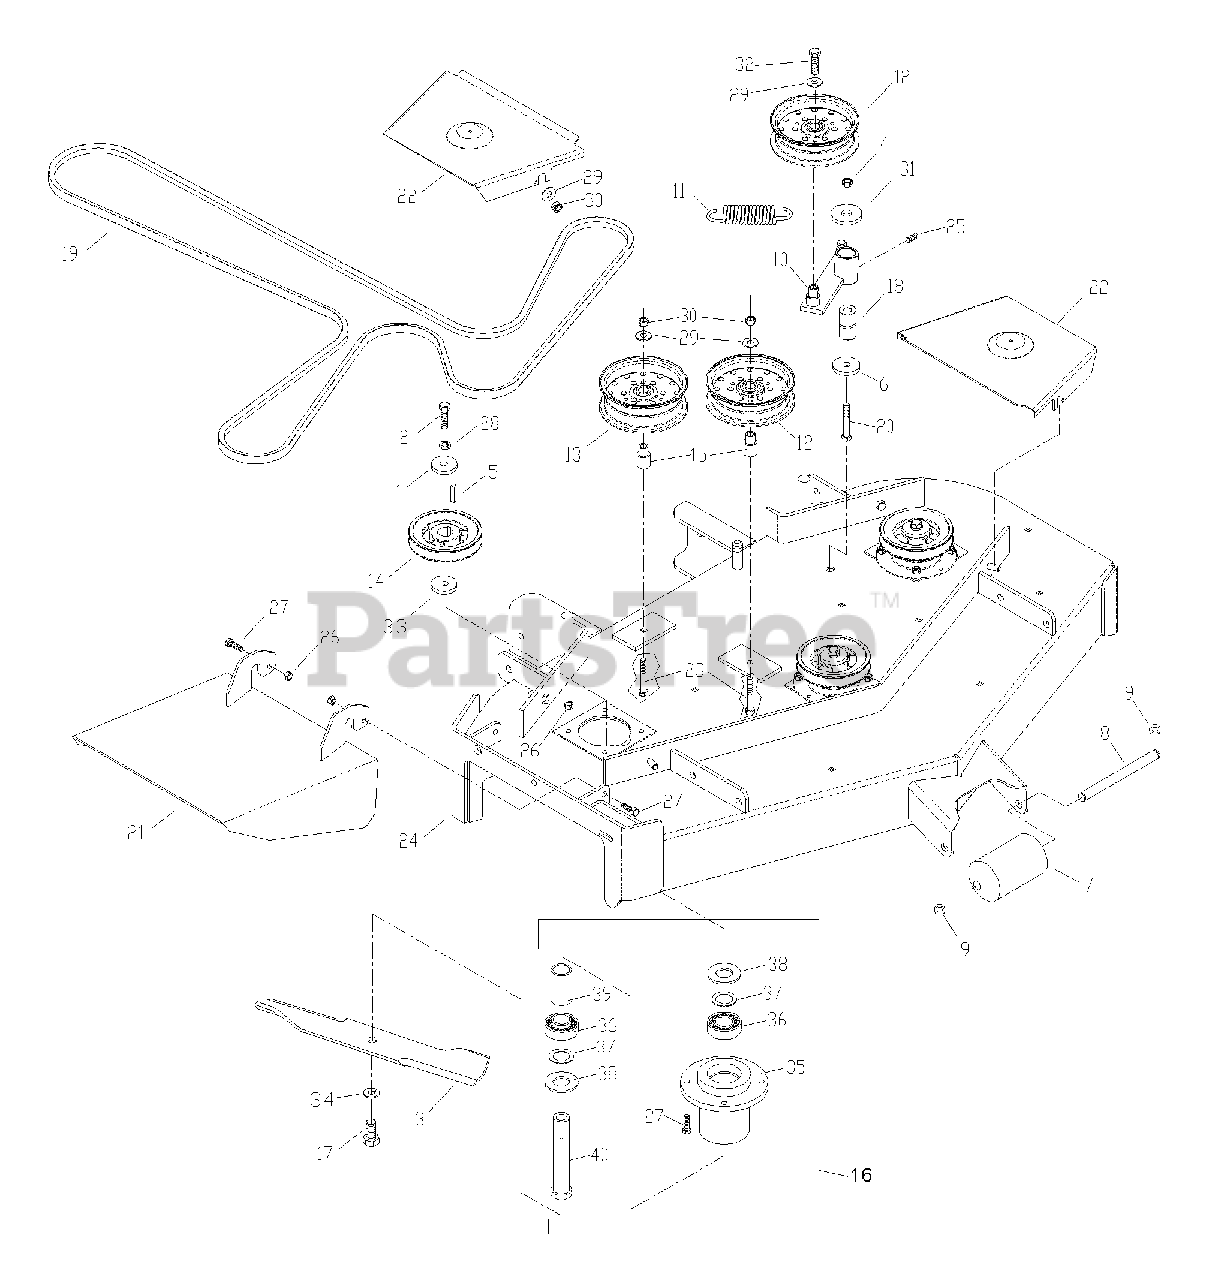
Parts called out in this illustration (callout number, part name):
1	HEAVY WASHER
2	HCS 7/16 X 1.500
3	BLADE 14.875
4	NUT 1/2 NYLOC
5	KEY 1/4 X 1.125
6	SUPPORT WASHER
7	ANTI-SCALP ROLLER
8	ROLLER AXLE
9	E-RING 1/2
12	IDLER PULLEY
13	IDLER PULLEY
15	IDLER BUSHING
16	COMPLETE HOUSING
17	HCS 5/16 X 1.250
18	PIVOT BUSHING
19	BELT
20	HCS 1/2 X 3.250
21	DEFLECTOR CHUTE
22	BELT SHIELD
23	HCS 3/8 X 2.500
24	DECK W/DECALS
25	ZERK
26	NUT 5/16 CTR. LOCK
27	HCS 5/16 X 1.000
28	WASHER 7/16 LOCK
29	WASHER 3/8 FLAT
30	NUT 3/8 CTR. LOCK
31	WASHER 1/2 FLAT
32	HCS 3/8 X 1.00 SERR. HD.
33	MACH. BUSHING
34	WASHER 5/8 LOCK
36	BEARING
37	MACH. BUSHING
38	MACH. BUSHING
41	MAIN BAFFLE
42	RHSNB 5/16 X .625
43	CENTER BAFFLE
44	WASHER 5/16 FLAT
45	HCS 5/16 X .750
